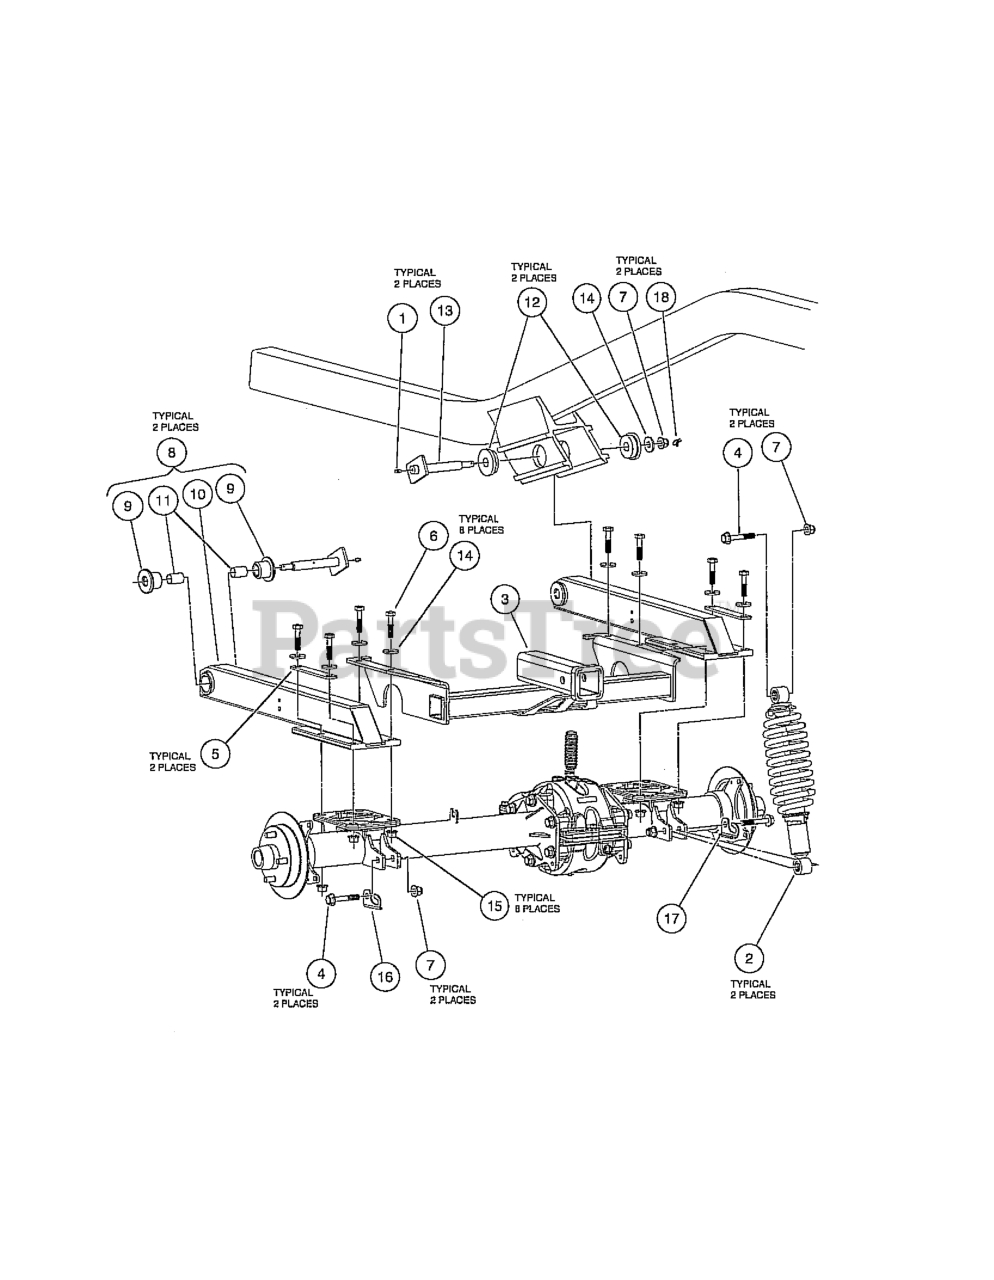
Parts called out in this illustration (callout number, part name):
1	FITTING, 1/4-28 THRD FRM GREAS
2	SHOCK, COIL OVER REAR
3	WELDMENT, RECEIVER, REAR
4	BOLT, FLG, M12X1.75X70
5	WASHER, STRIP, SWINGARM
6	BOLT FLG, M12X1.75X50
7	NUT FLG, M12X1.75, NYLON GR 10
9	BUSHING, PIVOT, URETHANE
10	WELDMENT SWINGARM
11	BUSHING, TEFLON
13	PIN, SWINGARM, WELDMENT
14	WASHER, M12 HARD REGULAR
16	BRKT, LINE, HYD, SHK MNT, DRV
17	BRKT, LINE, HYD, SHK MNT, PASS
18	COTTER-RUE RING
